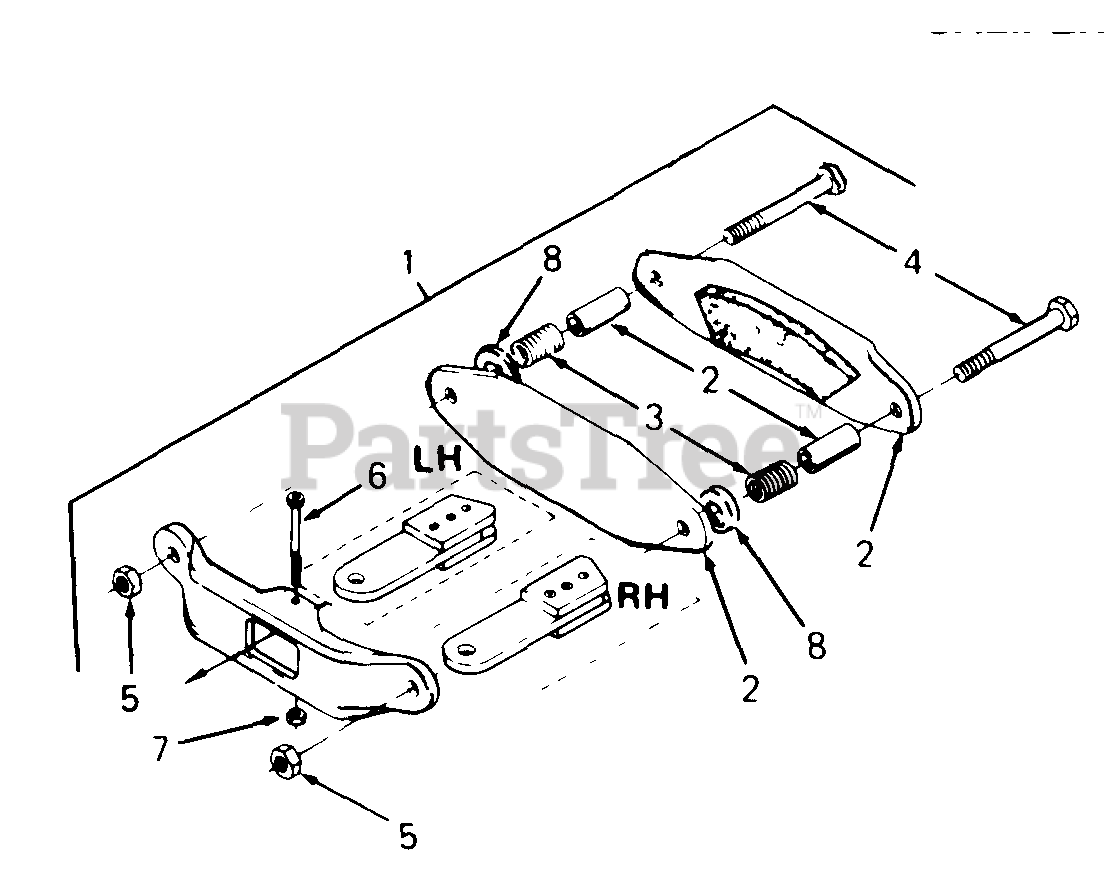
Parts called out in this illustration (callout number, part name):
1	Kit, Brake Caliper
2	Puck Kit, Brake
3	Spring, Compression
4	Screw, Hex Cap, 3/8-24 X 2.25 Lg
5	Nut, Hex Lock, 3/8-24 GR5
6	Screw, Socket Hd Shld, 1/4-20 X 1.25 Lg
7	Nut, Hex Top Lock Jam, 1/4-20 GR5
8	Washer, Flat, .390 X 1.0 X .030 Thk HDN
